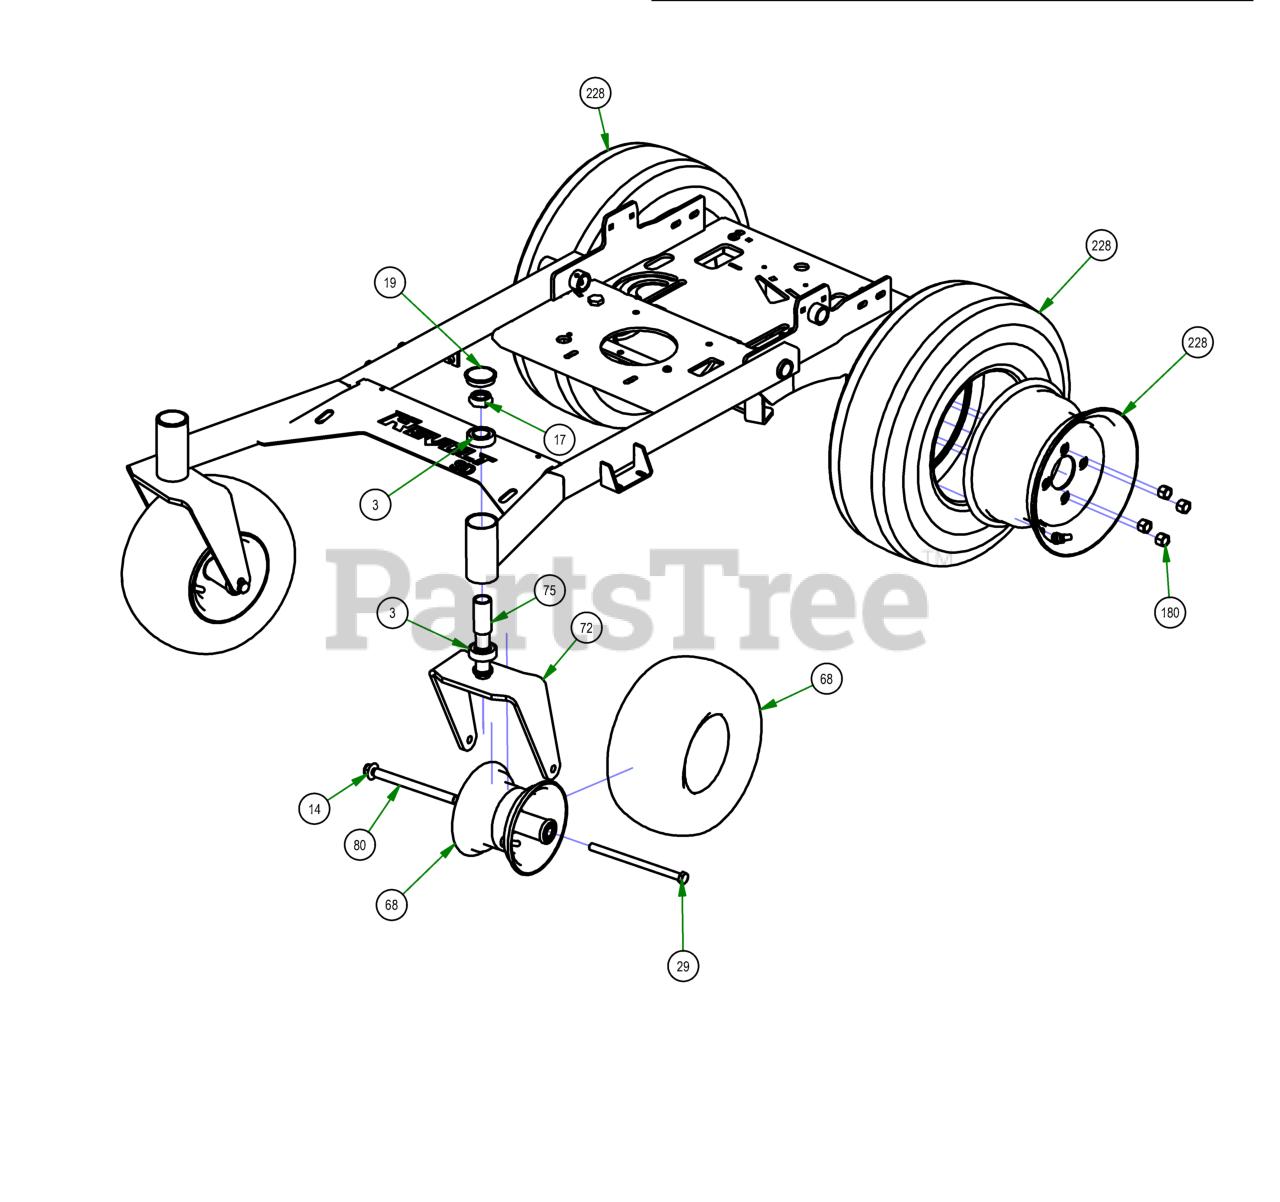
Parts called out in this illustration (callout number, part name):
3	1641 BEARING W/2 CONTACT RUBBER SEALS
14	1/2-13 Nylon Insert Flange Locknut
17	1" Fine Thread 1/2 Nylock Nut
18	5/16-18 Nylock Insert Jam Locknut
19	2017 Bearing Cover
25	1-14 x 5 Hex Bolt Grade 8 Zinc Yellow
29	1/2" x 8 1/2 GR 5 Hex Bolt
42	1/2'' Nylock Nut 1/2 Jam
56	1/2 F/W USS 1- 3/8'' OD
62	1/4 USS FLAT WASHER (3/4 OD) ZINC
68	13x6.5-6 Black Tire and Wheel Assembly
71	1 3/8" Wheel Bearing
72	2017 ZT Front Fork
74	1/4'' Press in Grease Fitting
75	2016 Front Bearing Spacer
80	Front Wheel Spanner
132	Spacer, 1x1.375x.25
145	2023 Stand On Frame Weldment -SD
180	Acorn Lug Nut
228	21/7x10 Reaper Tire-36 Revolt
